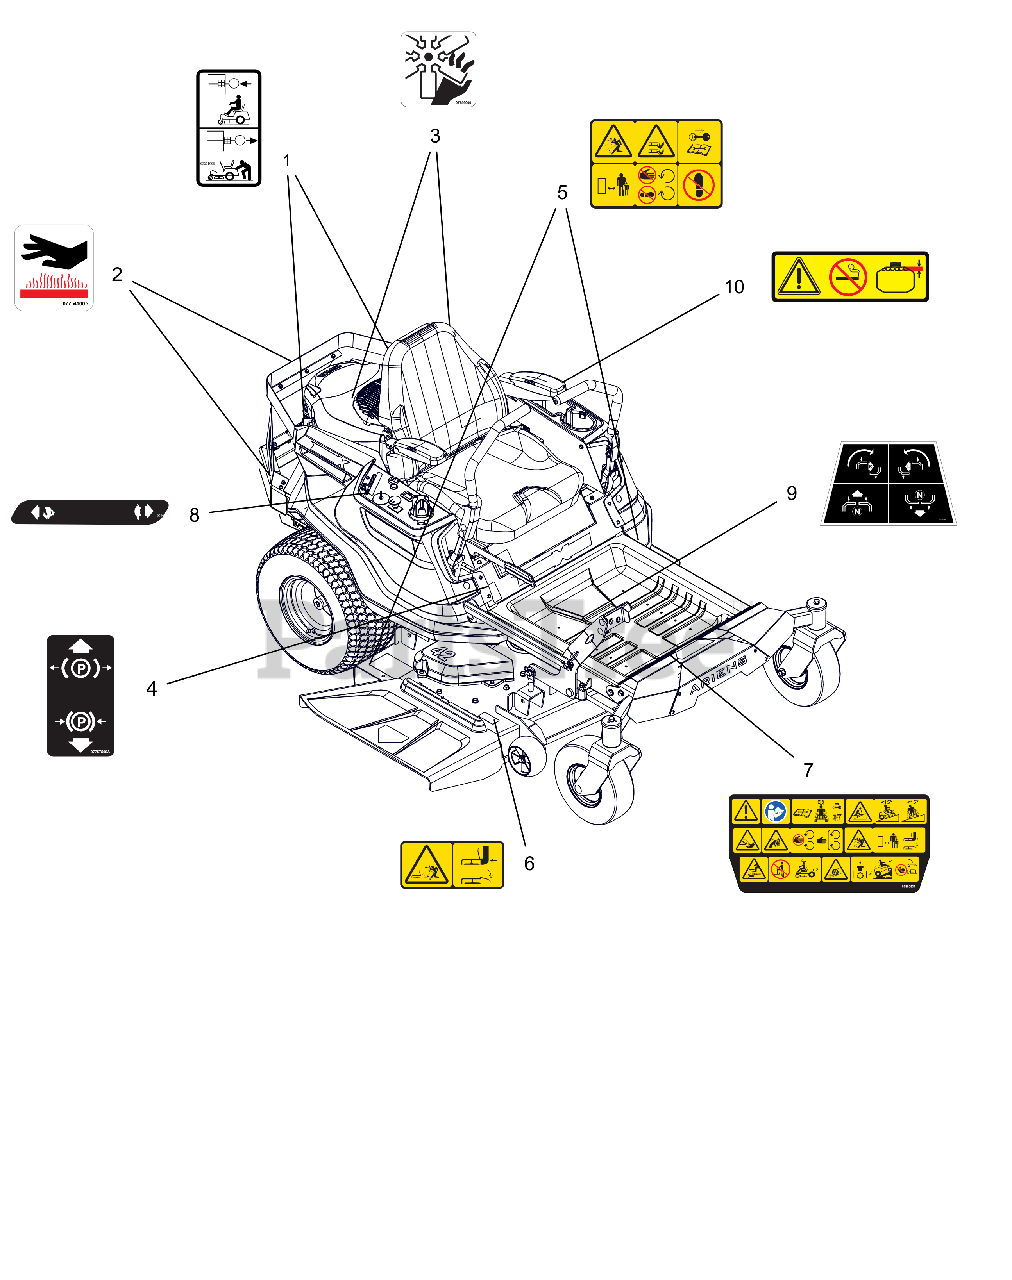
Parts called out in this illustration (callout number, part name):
1	DECAL, TRANSMISSION DISCONNECT
2	DECAL, HOT SURFACE
3	DECAL, DANGER FAN
4	DECAL, PARKING BRAKE LEVER
5	DECAL, SAFETY - MOWER DECK
6	DECAL, SAFETY - DECK GUARDING
7	DECAL, MAIN SAFETY
8	DECAL, DASH DECAL
9	DECAL, STEERING
10	DECAL, FUEL WARNING
